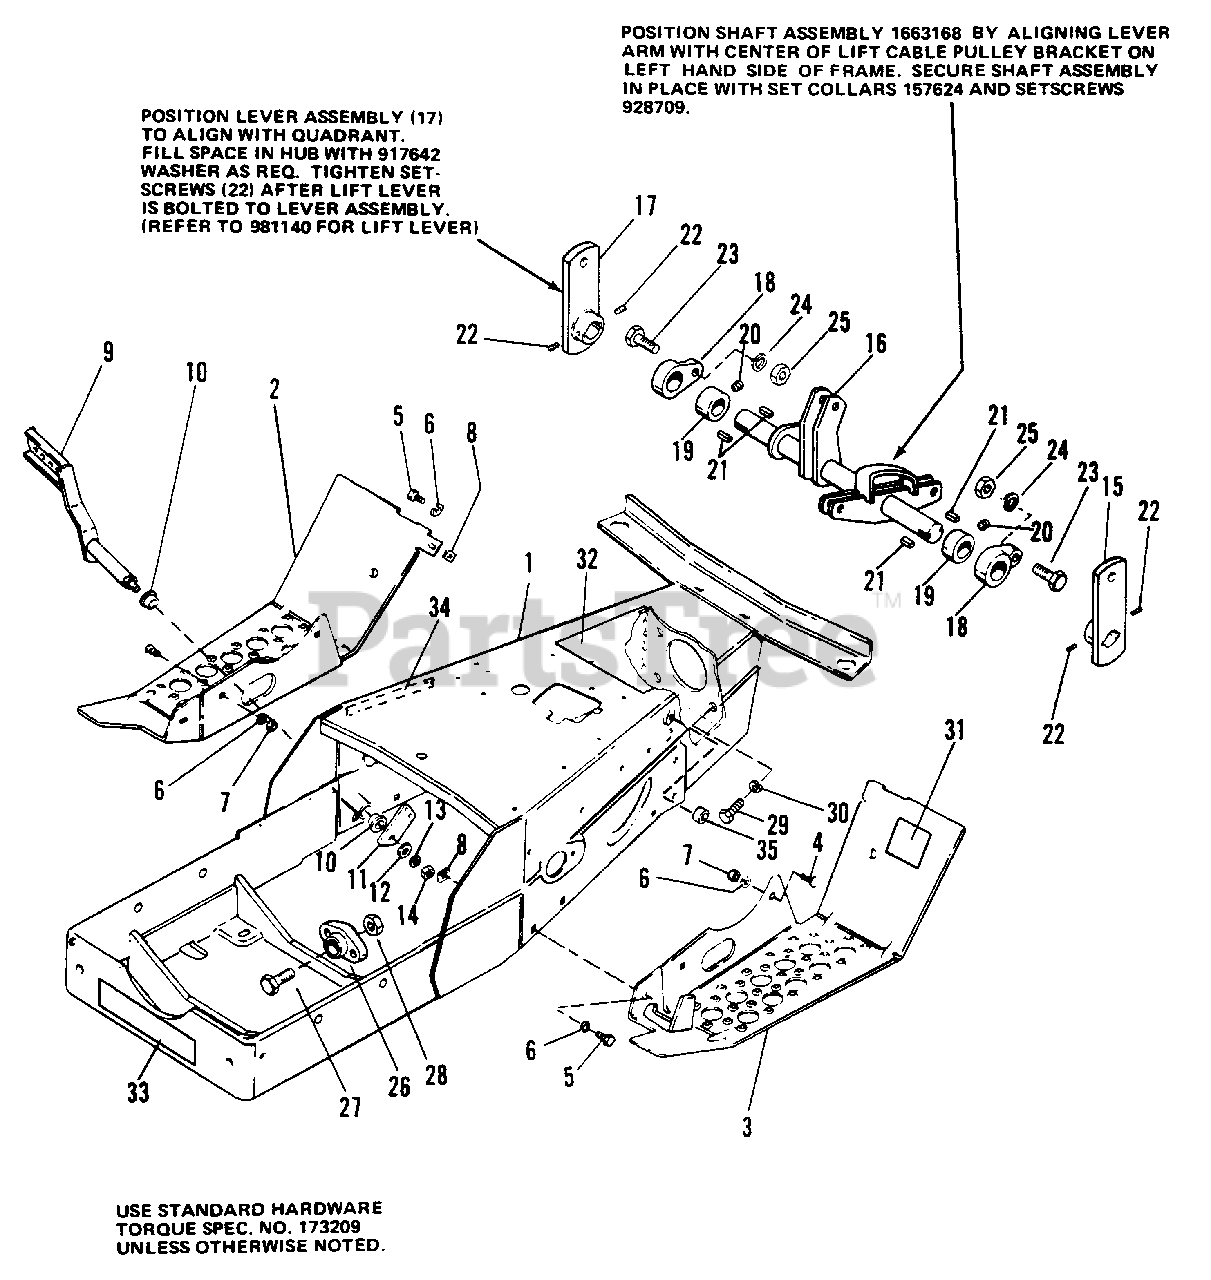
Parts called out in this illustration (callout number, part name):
1	REAR FRAME ASSEMBLY
2	FOOT REST, R.H.
3	FOOT REST, L.H.
4	BOLT, Carriage, 5/16-18 x 3/4
5	CAPSCREW, Hex Hd., 5/16-18 x 3/4
6	LOCKWASHER, 5/16
7	NUT, Hex, Full, 5/16-18
8	NUT, Speed, Tinn., 5/16-18
9	FOOT PEDAL ASSEMBLY
11	ARM, Pedal Foot
12	WASHER, 3/8
13	LOCKWASHER, 3/8
14	NUT, Hex, Full, 3/8-16
15	FRONT LIFT LEVER ASSEMBLY
16	LIFT SHAFT ASSEMBLY
17	LIFT LEVER ASSEMBLY
18	BEARING, Lift Lever
19	SET, Collar
20	SETSCREW, Cup Pt., 5/16-18 x 3/8
22	SETSCREW, Soc. Hd., 5/16-18 x 1/4
23	CAPSCREW, Hex Hd., 5/16-18 x 1-1/4
24	LOCKWASHER, 5/16
25	NUT, Hex, full, 5/16-18
26	BEARING, Pivot
27	CAPSCREW, Whiz, 3/8-16 x 1-1/4
28	NUT, Flange, 3/8-16
29	CAPSCREW, Hex Hd., 7/16-14 x 1-1/2
30	LOCKWASHER, 7/16
31	DECAL, Parking Brake
32	PLATE, Safety
33	DECAL, Simplicity
34	DECAL, Clutch
